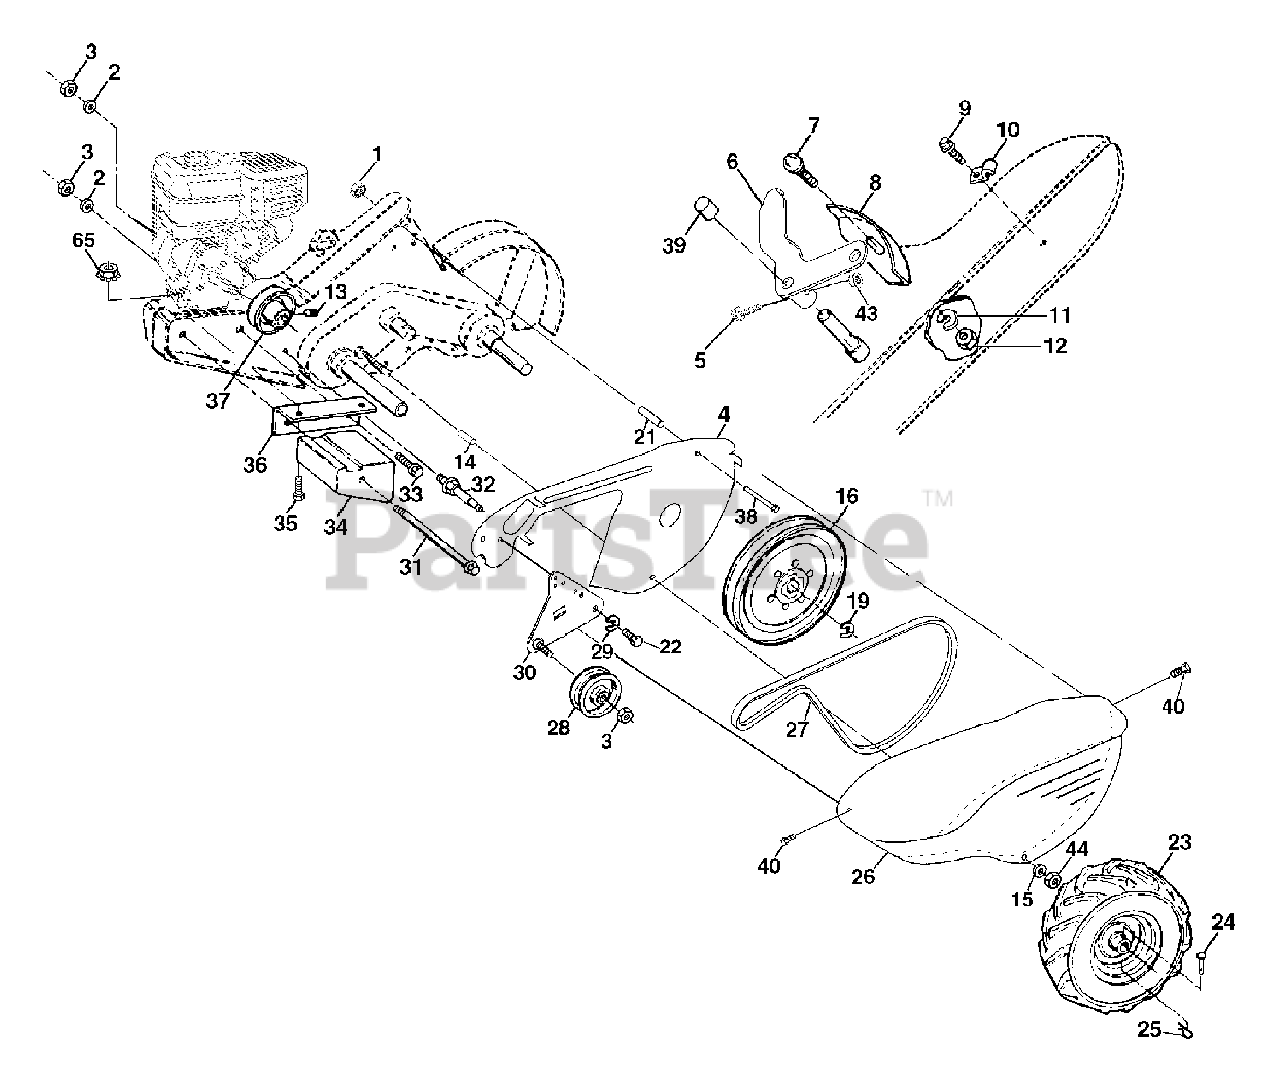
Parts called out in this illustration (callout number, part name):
1	Nut, Keps 5/16-18
2	Washer, Lock 3/8
3	Nut, Hex 3/8-16
4	Shield, Inner Belt Guard RT
5	Screw, Shift Lever
6	Lever, Shift
7	Bolt, Carriage 1/4-20 x 1/2 Gr. 5
8	Plate, Shift Indicator
9	Screw, Hex, Washer Head, Slotted #10-24 x 1/2
10	Clip
11	Washer, Lock 1/4
12	Nut, Hex 1/4-20
13	Screw, Set, Hex 5/16-18 x 3/8
14	Spacer, Split 0.327 x 0.42 x 1.220
15	Washer 11/32 x 11/16 x 16 Ga.
16	Sheave, Transmission
19	Retainer, Ring
21	Spacer, Split 0.327 x 0.42 x 2.09
22	Bolt, Fin Hex 5/16-24 UNF x 1/2
23	Tire
23	Rim
23	Tire Valve
24	Rivet, Drilled
25	Clip, Hairpin
26	Guard, Belt
27	Belt, V
28	Pulley, Idler
29	Ring, Klip
30	Bracket, Idler
31	Bolt, Hex 5/16-16 x 12
32	Shaft, Idler Arm
33	Bolt, Hex 3/8-16 x 1
34	Counterweight, L. H.
35	Bolt, Hex 5/16-18 x 2
36	Bracket, Reinforcement, L. H.
37	Sheave, Engine
38	Bolt, Fin Hex 5/16-18 UNC x 2-3/4
39	Cap, Plunger Blk
40	Screw Hex Wsh Slt #10-24 x 1/2
43	Nut, Lock #10-24
44	Nut Lock Hex w/Ins 5/16-18 Unc PL
65	Nut Lock Hex Flange
